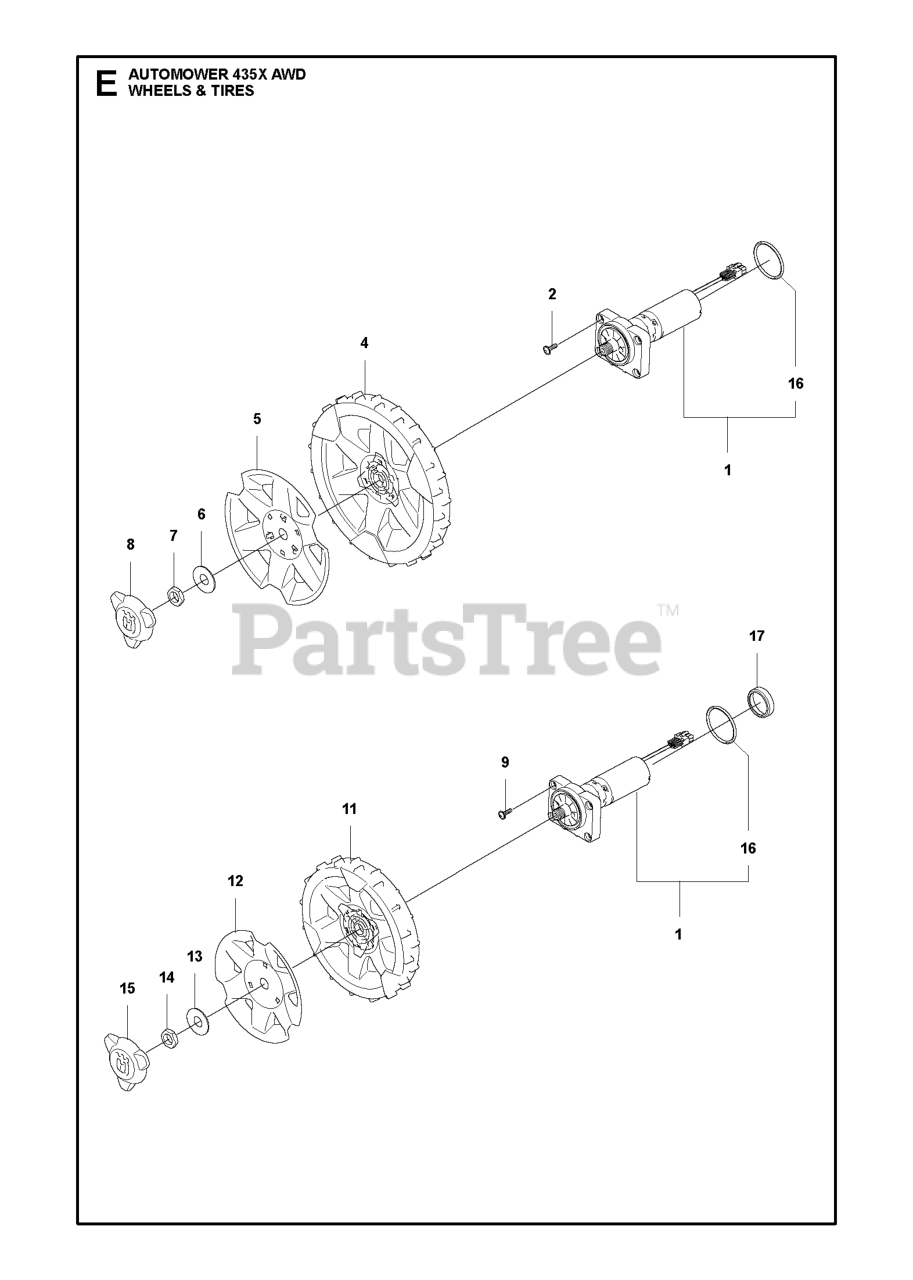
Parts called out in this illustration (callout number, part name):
2	SCREW ITXPANT
5	WHEEL COVER REAR WHEEL
6	WASHER WASHER REAR WHEEL 16X40
7	HEXAGON THIN NUT
8	HUB CAP REAR WHEEL NO CENTER P
9	SCREW ITXPANT
12	WHEEL COVER PAINTED
13	WASHER WASHER REAR WHEEL 16X40
14	HEXAGON THIN NUT
15	HUB CAP REAR WHEEL NO CENTER P
16	O-RING LIGHT GREY
